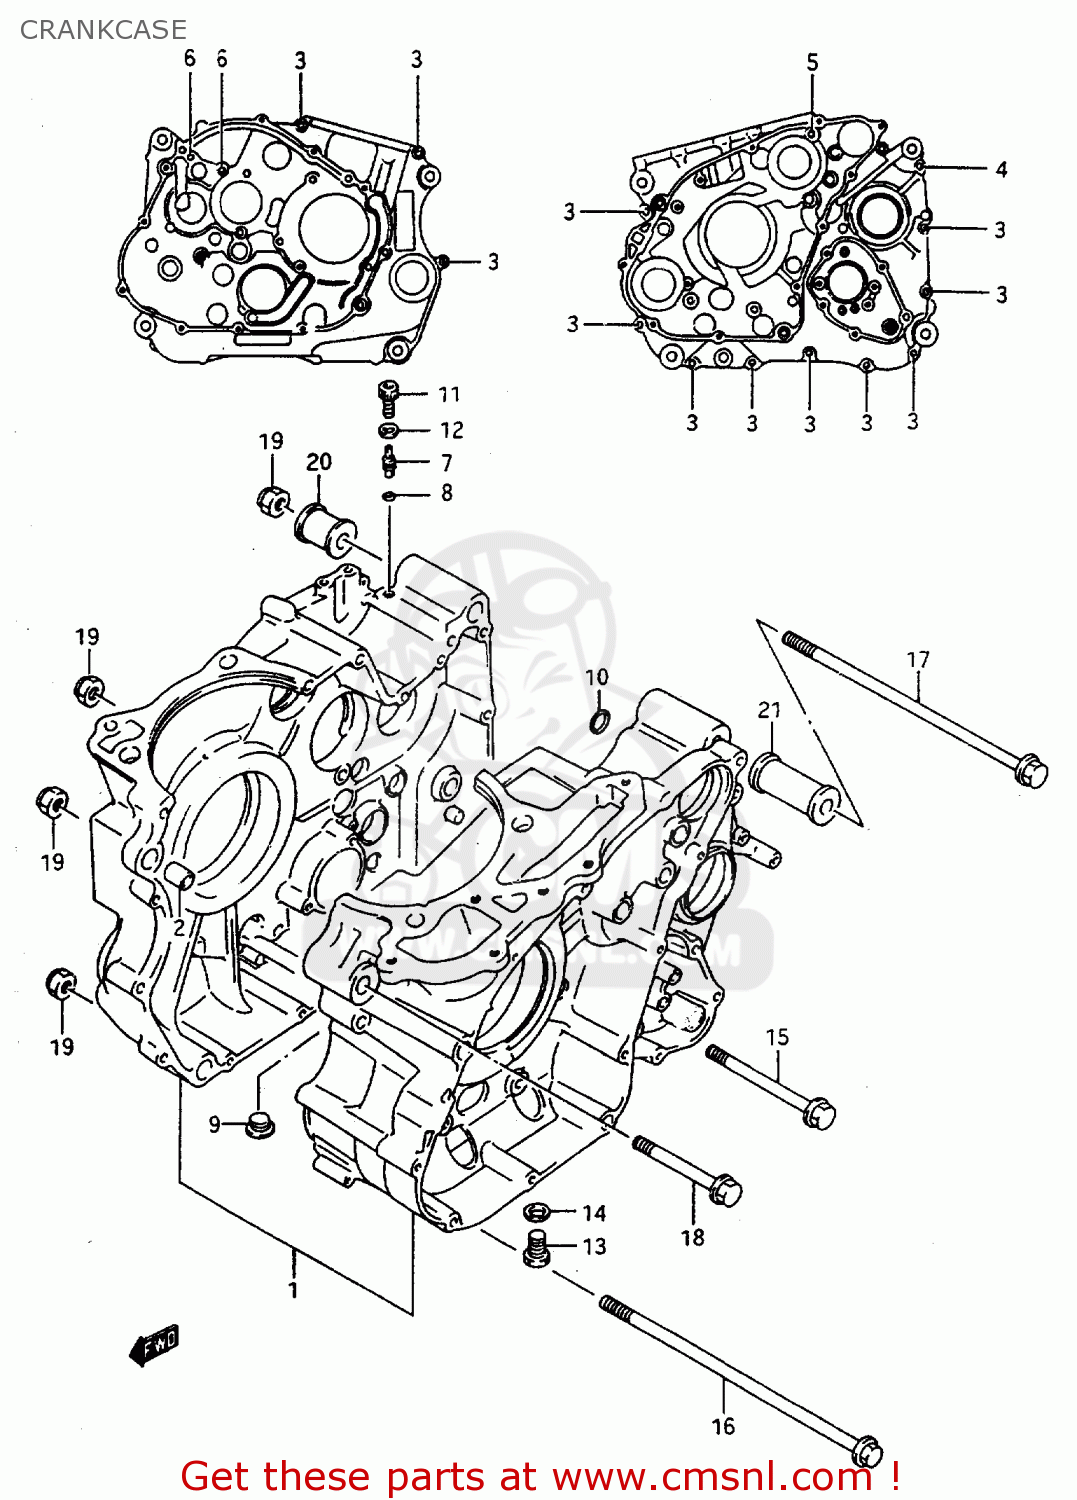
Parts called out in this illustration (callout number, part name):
1	CRANKCASE SET
2	PIN
3	BOLT
4	BOLT
5	BOLT
6	BOLT
7	JET(12)
8	O RING(D:1.2,ID:4)
9	PLUG
10	O RING(D:1.9,ID:11)
11	BOLT
12	GASKET 8.2X14X1 (NAS)
13	BOLT
14	GASKET(12.1X16.2X3.7) (NAS)
15	BOLT(10X130)
16	BOLT (10X215)
17	BOLT 10X230
18	BOLT 10X70
19	NUT
20	SPACER,ENGINE MOUNT
21	SPACER,ENG MTG,R(L:60)
